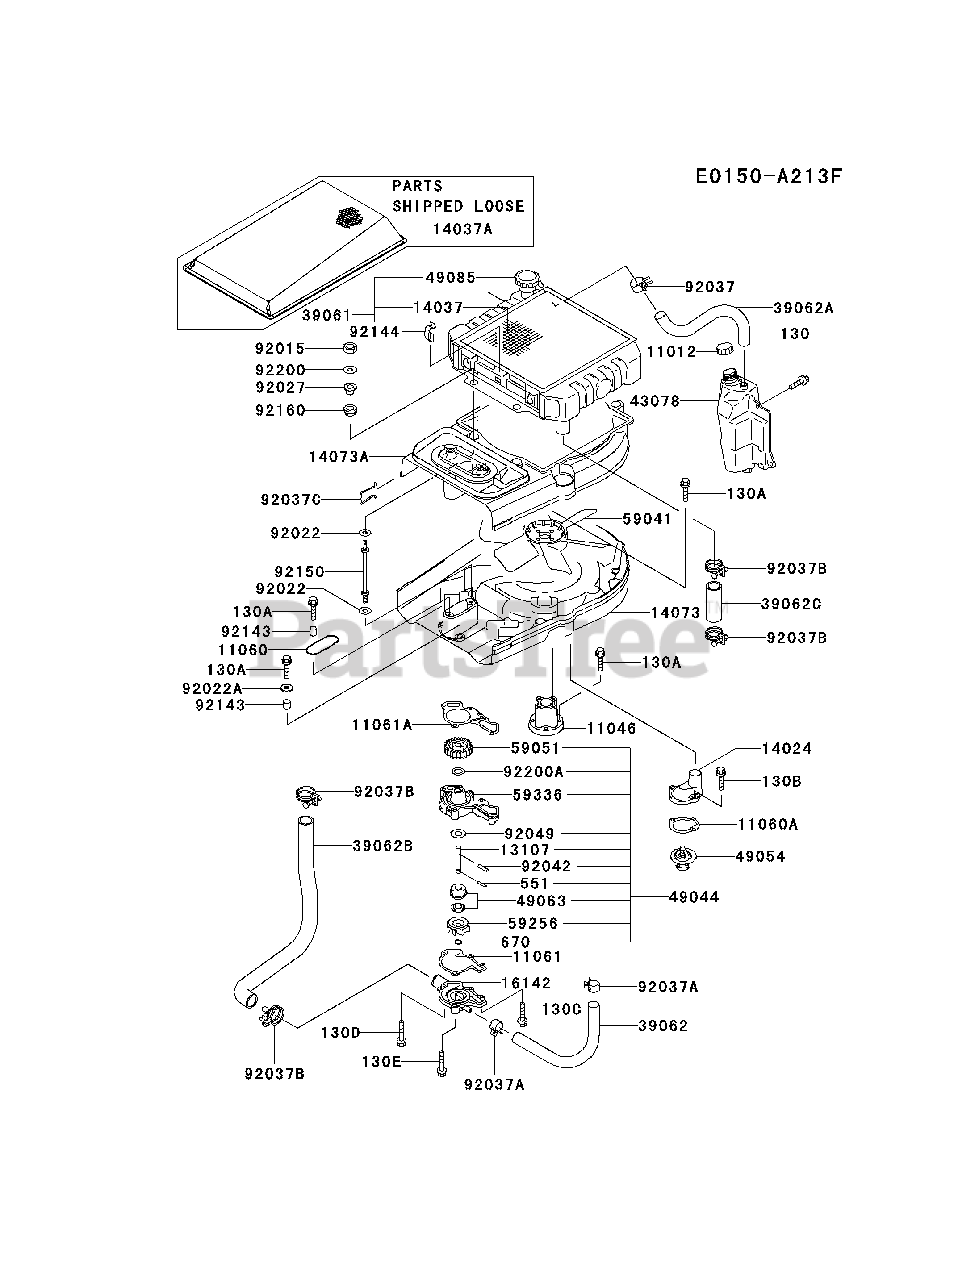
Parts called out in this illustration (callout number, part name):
130	BOLT-FLANGED,6X14
130A	BOLT-FLANGED,6X20
130B	BOLT-FLANGED,6X20
130C	BOLT-FLANGED,6X45
130D	BOLT-FLANGED,6X80
130E	BOLT-FLANGED,8X75
551	PIN-DOWEL,3X14
670	O RING,7MM
